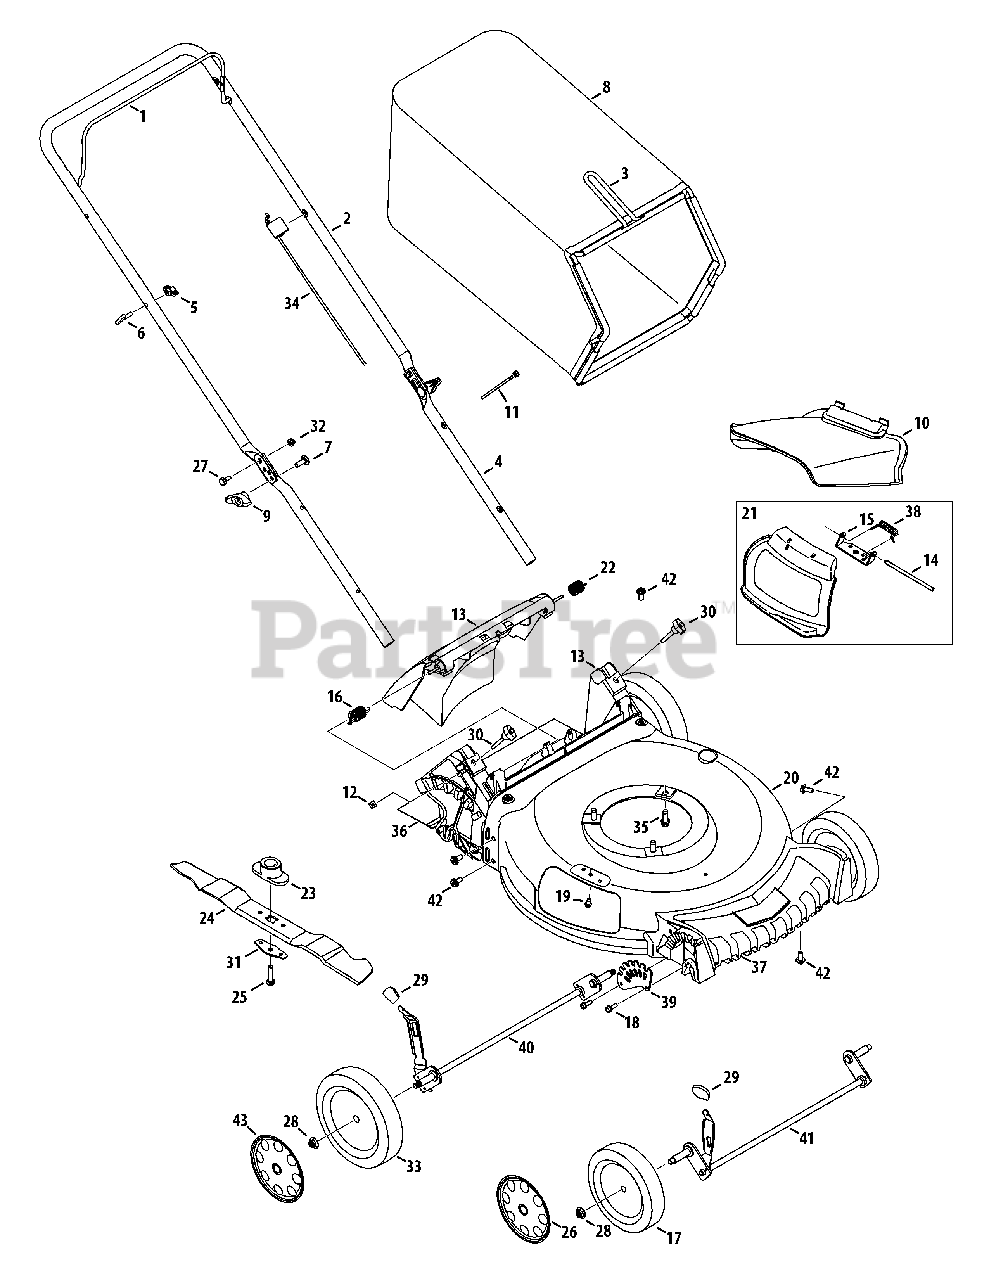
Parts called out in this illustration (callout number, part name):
1	Blade Control
2	Upper Handle
3	Grass Catcher Frame
4	Lower Handle
6	Rope Guide
7	Carriage Screw, 5/16-18
8	Grass Bag
10	Side Chute
11	Cable Tie
12	Nut, Sq., 1/4-20
13	Rear Discharge Door Assembly
15	Chute Deflector Bracket
16	Torsion Spring - RH
17	Front Wheel
18	Screw, 1/4-15 x .750
19	Screw, 1/4-20 x .500
20	Deck , 21"
21	Hinged Mulch Plug Assembly
22	Torsion Spring - LH
23	Blade Adapter
24	Mulching Blade
25	Screw , 3/8-24 x 1.50
26	Hub Cap, 7"
27	Sldr. Screw, .375 x .126 x 1/4-20
28	Flange Lock Nut, 3/8-16
29	Adjustment Lever Knob
30	Wing Nut
31	Blade Bell Support
32	Nut, Flange Lock, 1/4-20
33	Rear Wheel
34	Control Cable
35	TT Sems Screw, 3/8-16 x 1.0
36	Trail Shield
37	Front Cover
38	Torsion Spring
39	Front Height Adjuster Plate
40	Rear Axle Assembly
41	Front Axle Assembly
42	Screw, 5/16-14 x .750
43	Hub Cap, 8"
